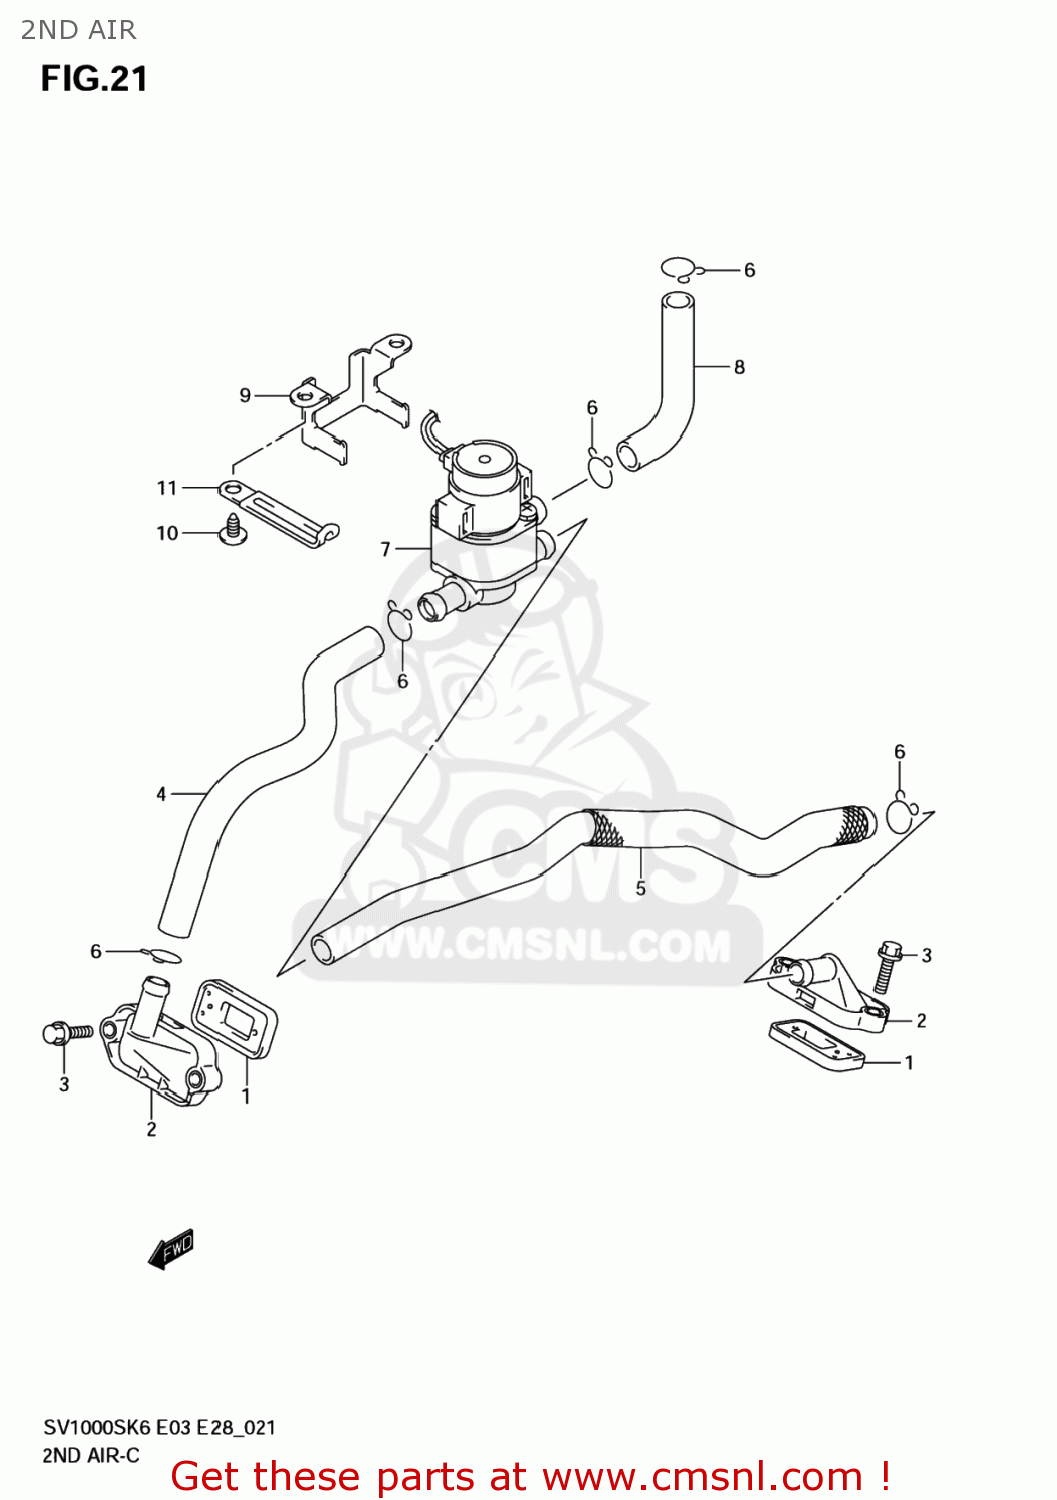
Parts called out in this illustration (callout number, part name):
1	VALVE ASSY,2ND AIR REED
2	COVER,2ND AIR
3	BOLT(6X20)
4	HOSE,2ND AIR VALVE FR
5	HOSE,2ND AIR VALVE RR
6	CLIP
7	VALVE ASSY,AIR CUT
8	HOSE,2ND AIR CLEANER
9	BRACKET,2ND AIR VALVE
10	SCREW
11	CLAMP(L:45)
